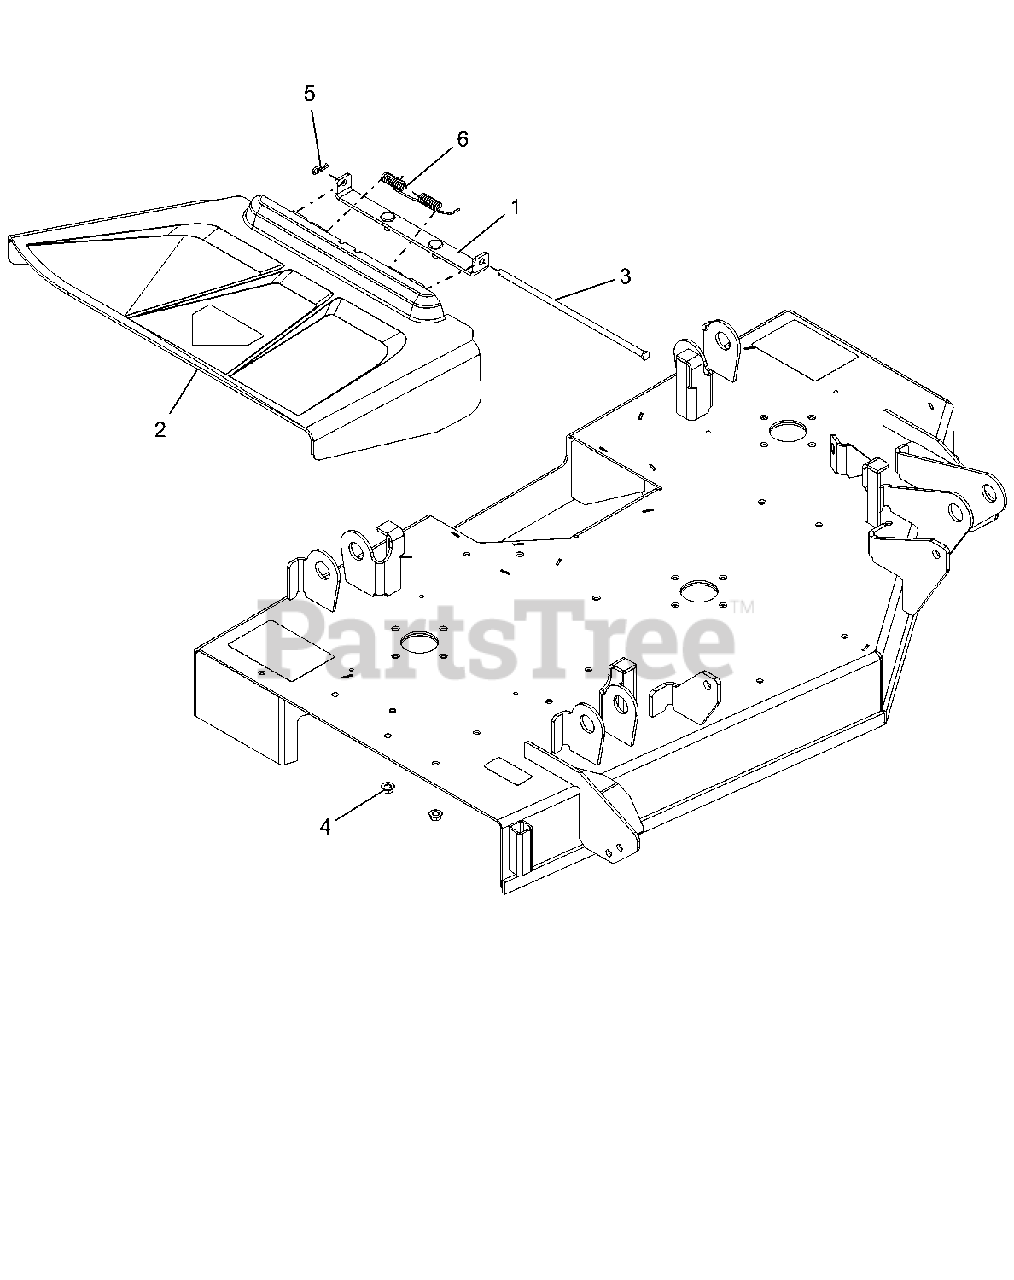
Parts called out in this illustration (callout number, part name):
1	WLDMT, CHUTE MOUNTING BRACKET (RED)
2	CHUTE, SIDE DISCHARGE
3	PIN, 5/16 X 10.5
4	NUT, LK-TOP-FLG .312-18 YWZC
5	PIN, HAIR INT .08X.18X1.18 YWZC
6	SPRG, TORSION .35 ID (CHUTE)
